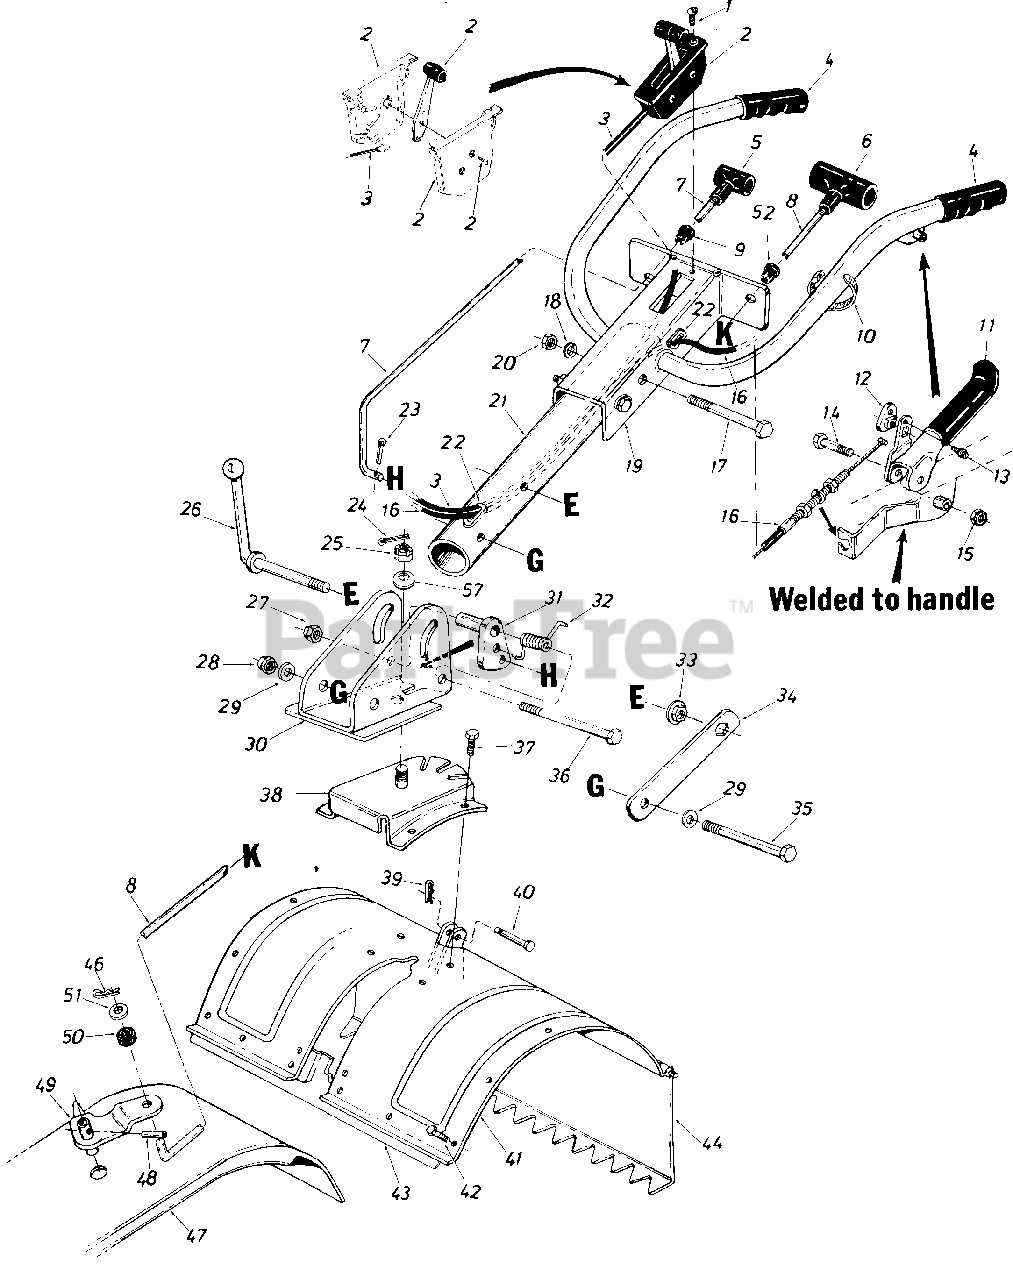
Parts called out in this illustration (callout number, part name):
1	Truss Mach. AB-Tap. Scr. #10 x .50" Lg.
2	Throttle Control Box Ass'y.
3	Throttle Control Wire
4	Handle Grip
5	Small "T" Knob
6	Large "T" Knob
7	Clutch Rod
8	Control Rod 37" Lg.
9	Snap On Bushing 3/8" Dia.
10	Cable Tie-Self Clinching
11	Clutch Grip Ass'y. L.H.
12	Barrel Cable Hold Down
13	Hex B-Tap Scr. #10 x .44" Lg.
14	Hex Bolt 3/8-16 x 2.0" Lg.
15	Hex Cent. L-Nut 3/8-16 Thd.
16	Clutch Control Cable 53" Lg.
17	Hex Bolt 3/8-16 x 3.00" Lg.
18	L-Wash. 3/8" I.D. H.D.
23	Cotter Pin 3132" Dia. x .75" Lg.
24	Cotter Pin 3/32" Dia. x 1.25" Lg.
25	Hex Slotted Nut 5/8-18 Thd.
26	Handle Adj. Crank
27	Hex Cent. L-Nut 3/8-16 Thd.
28	Hex Nut 3/8-16 Thd.
29	Bell-Wash. .400" I.D. x .87" O.D.
30	Handle Pivot Bracket
31	Positioner Crank Ass'y.
32	Spring Handle Adj.
33	Hex Flange Nut 3/8-24 Thd.
34	Bracket Hex Nut Retainer
35	Hex Bolt 3/8-16 x 3.25" Lg.
36	Hex Bolt 3/8-16 x 3.00" Lg. Gr. 8
37	Hex Bolt 3/8-16 x .75" Lg.
38	Handle Positioner Brkt. Ass'y.
39	Intern. Cotter Pin
40	Clevis Pin .375" Dia.
43	Bracket Reinforcement 18"
46	Intern. Cotter Pin 5/16" Dia.
47	Shift Cover
48	Spring Roll Pin 3/16" Dia. x 1.00" Lg.
49	Shifting Crank Ass'y. D x 2.05
50	Rubber Washer .33" I.D. x .87" O.D.
51	Fl-Wash. .400" I.D. x 1.250" O.D.
52	Snap On Bushing 1/2" Dia.
57	Bell-Wash. .630" I.D. x 1.25" O.D.
